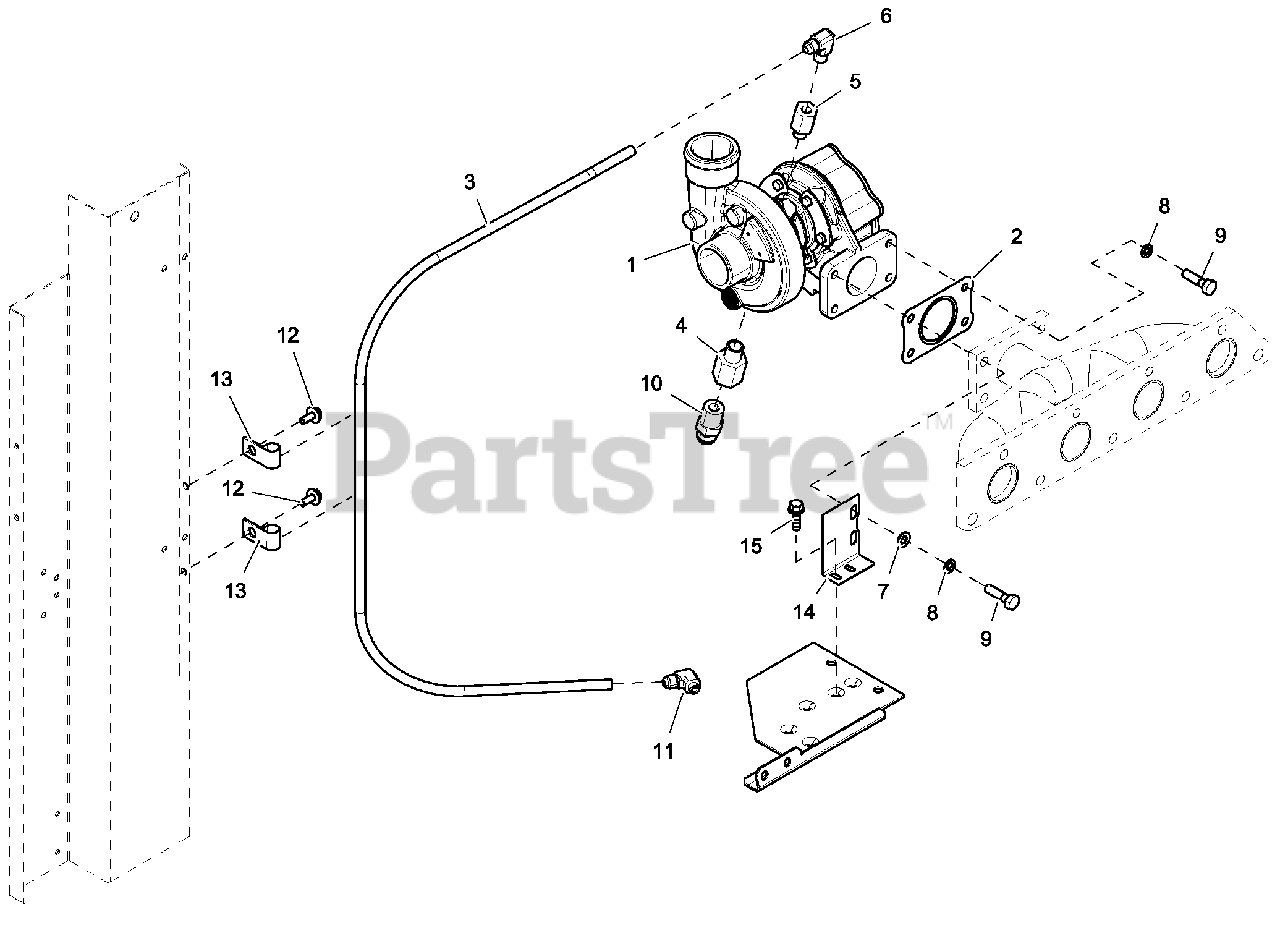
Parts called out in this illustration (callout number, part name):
1	TURBOCHARGER 2.4L 36KW 1800RPM
2	GASKET EXH MAN/TURBO
3	OIL SUPPLY 3LHA(38")
4	ADAPTER 1/2NPTX M16-1.5
5	ADAPTER 1/4NPTX M12-1.5
6	ADAPTER 90D JIC37 1/4NPT X 1/2
7	WASHER FLAT .34IDX .75OD
8	WASHER LOCK M8 SS
9	SCREW HHC M8-1.25 X 35 SS FTH
10	ADAPTOR 1/2 NPT X37JIC 3/4-16
11	ADAPTER 90D JIC37 1/8NPT X 1/2
12	SCREW THF M6-1 X 16 N WAZ/JS
13	CLAMP STL/VNL .5 X .406 Z
14	BRKT-EXH MANF 2.4L G2 36KW
15	SCREW HHTT M6-1.0 X 12 ZINC
